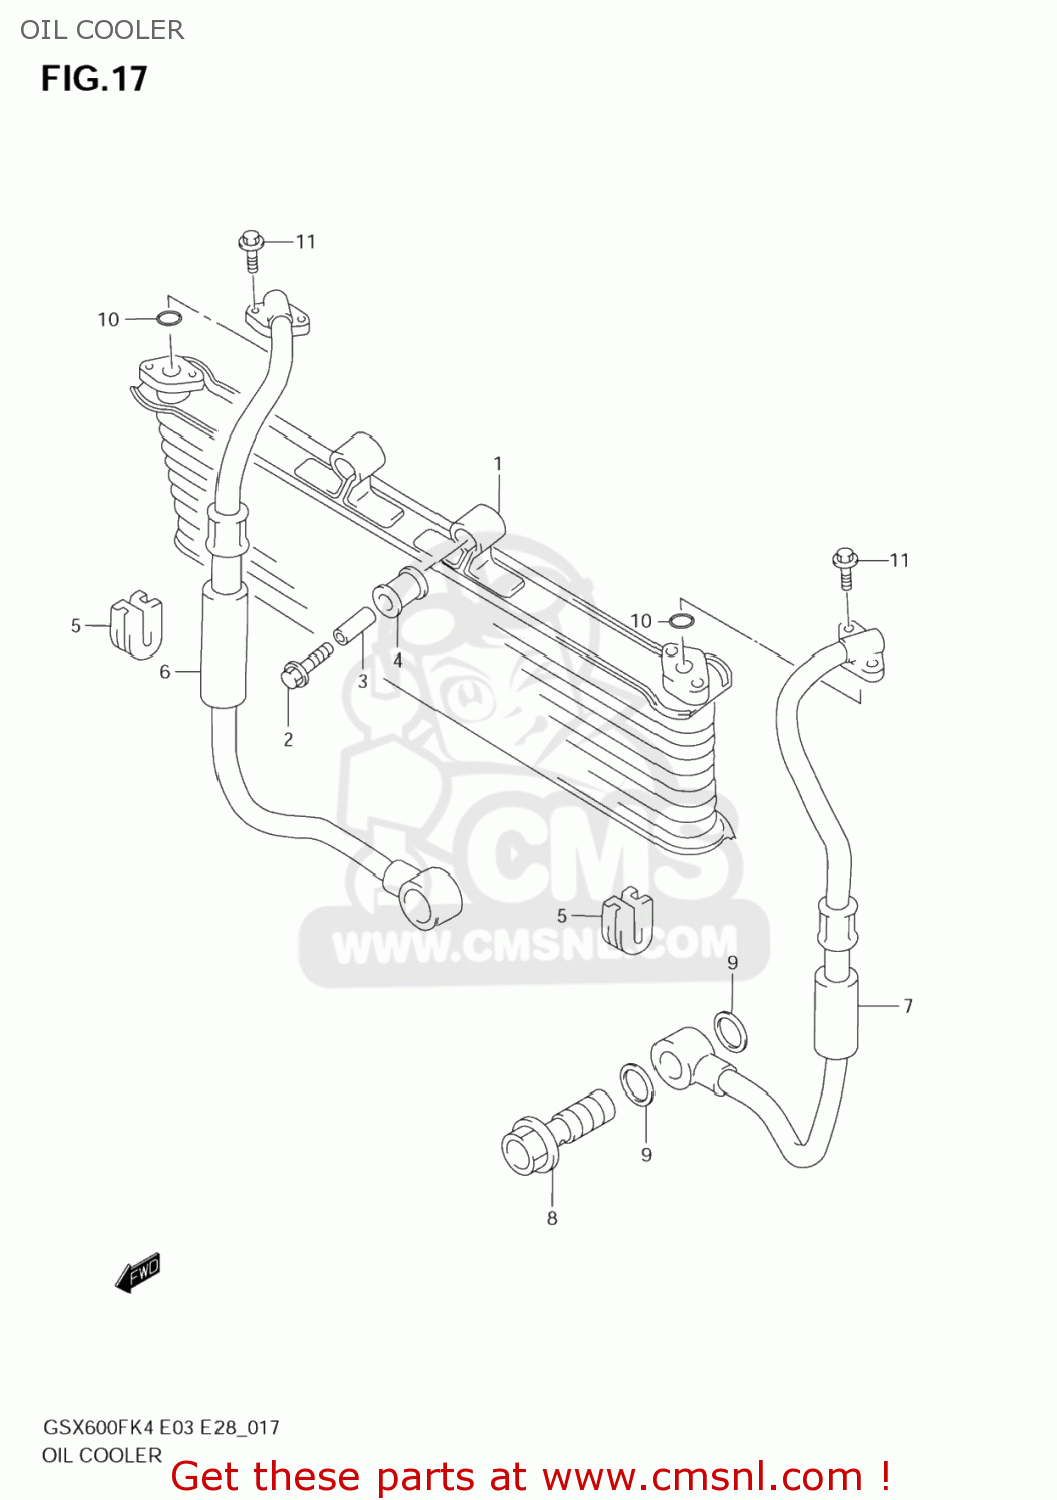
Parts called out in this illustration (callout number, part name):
1	COOLER ASSY,OIL
2	BOLT(8X40)
3	SPACER(8.5X12X25)
4	CUSHION,OIL COOLER NO.1
5	CUSHION,OIL COOLER NO.2
6	HOSE,OIL COOLER,R
7	HOSE,OIL COOLER,L
8	BOLT UNION
9	GASKET(16X22X2) (NAS)
10	O RING(D:2.4,ID:11.8)
11	BOLT,OIL FILLE
